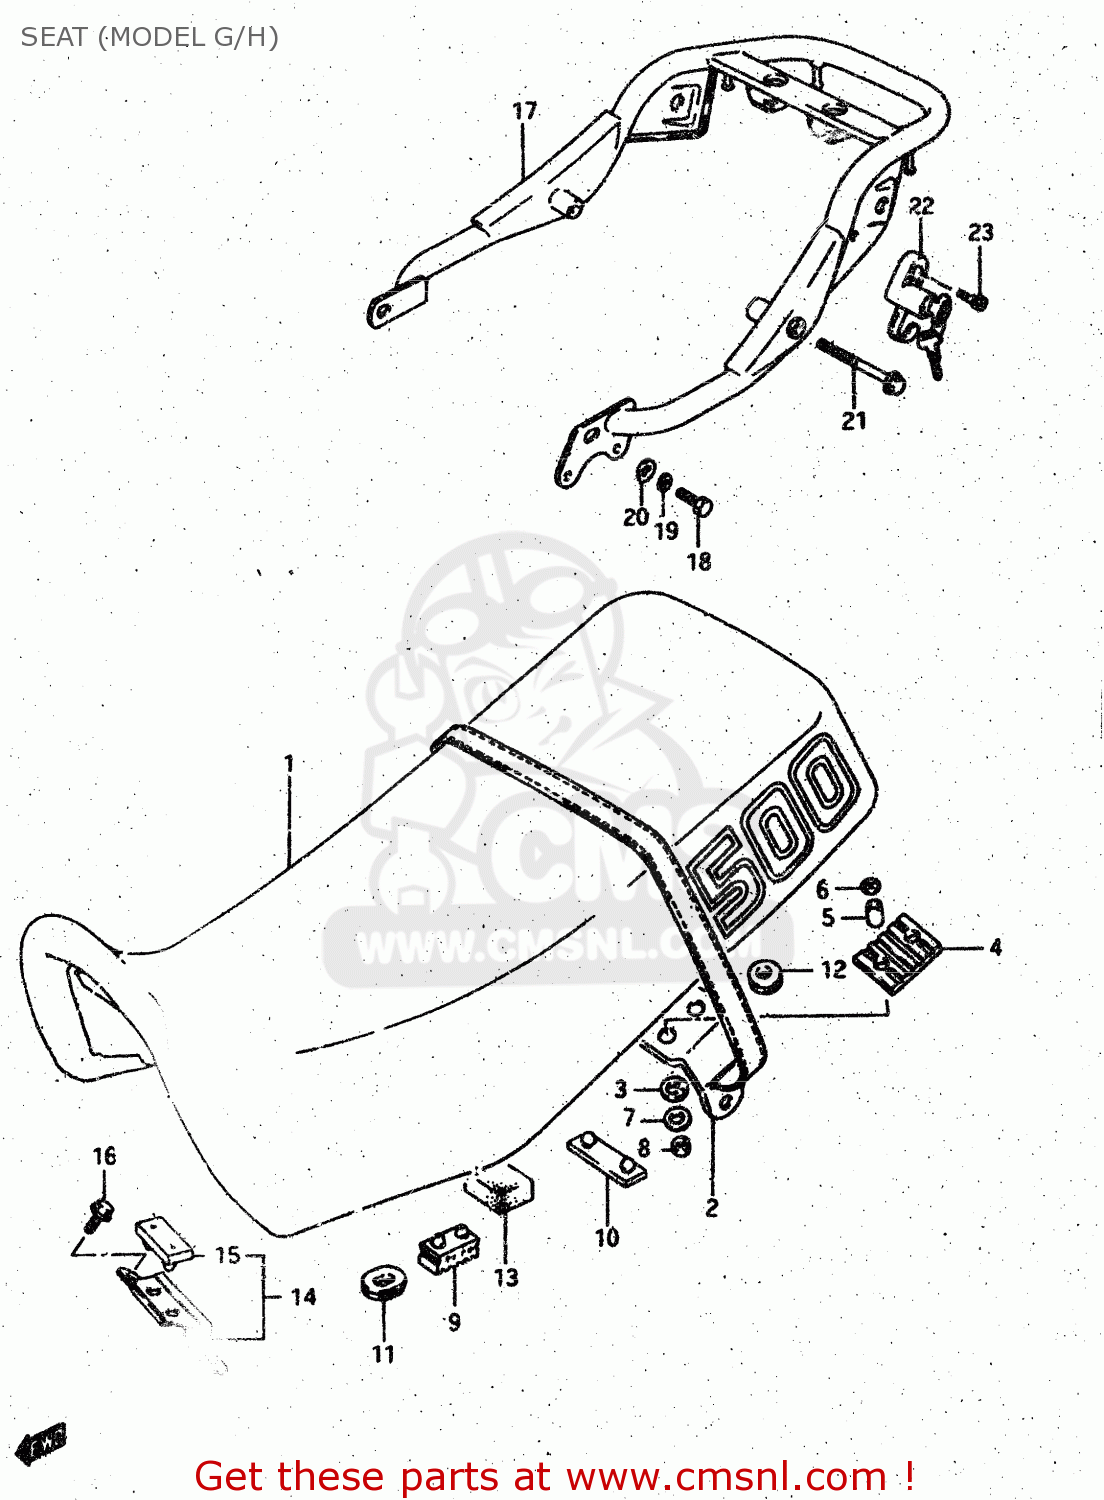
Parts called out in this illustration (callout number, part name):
1	SEAT SET (BLUE)
2	BAND, SEAT GRIP (BLUE)
3	CUSHION,SEAT FR
4	CUSHION,FR PLATE
5	SPACER,SEAT SUPPORT
6	WASHER
7	WASHER, LOWER
8	NUT
9	CUSHION,SEAT(40X20X15)
10	CUSHION
11	CUSHION
12	CUSHION
13	CUSHION,TOOL(40X30X15)
14	PLATE ASSY,SEAT FR HOOK
15	CUSHION
16	BOLT
17	CARRIER, SPORT (BLACK)
18	BOLT
19	LOCK WASHER
20	WASHER
21	BOLT (8X70)
22	LOCK SET
23	BOLT
